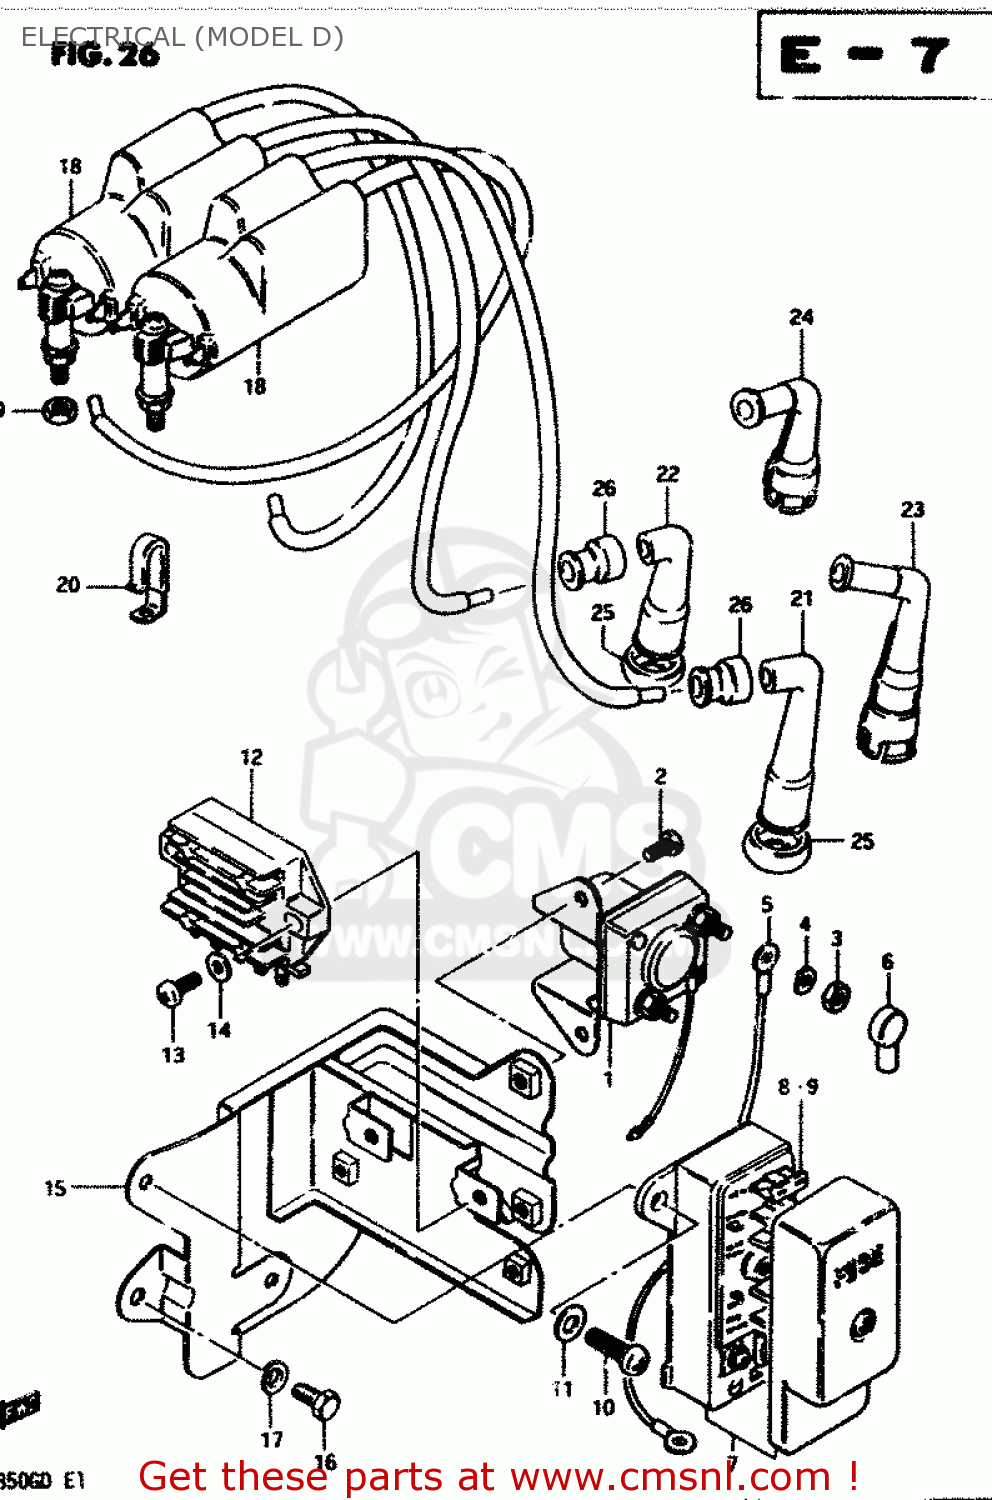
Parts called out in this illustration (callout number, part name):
1	RELAY ASSY,STARTING MOTOR
2	SCREW
3	NUT 6MM
4	LOCK WASHER
5	CABLE,STARTING MOTOR
6	CAP,STARTER RELAY
7	BOX ASSEMBLY,FUSE
8	FUSE(10A)
9	FUSE(15A)
10	SCREW 6X12
11	WASHER
12	RECTIFIER ASSEMBLY
13	SCREW
14	WASHER
15	HOLDER COMP,ELECTRONIC PARTS
16	BOLT
17	LOCK WASHER
18	COIL ASSEMBLY,IGNITION
19	NUT
20	CLAMP
21	CAP ASSY,SPARK PLUG
22	CAP,SPARK PLUG
23	CAP,SPARK PLUG
24	CAP, SPARK PLUG (S)
25	SEAL,SPARK PLUG
26	SEAL,SPARK PLU
